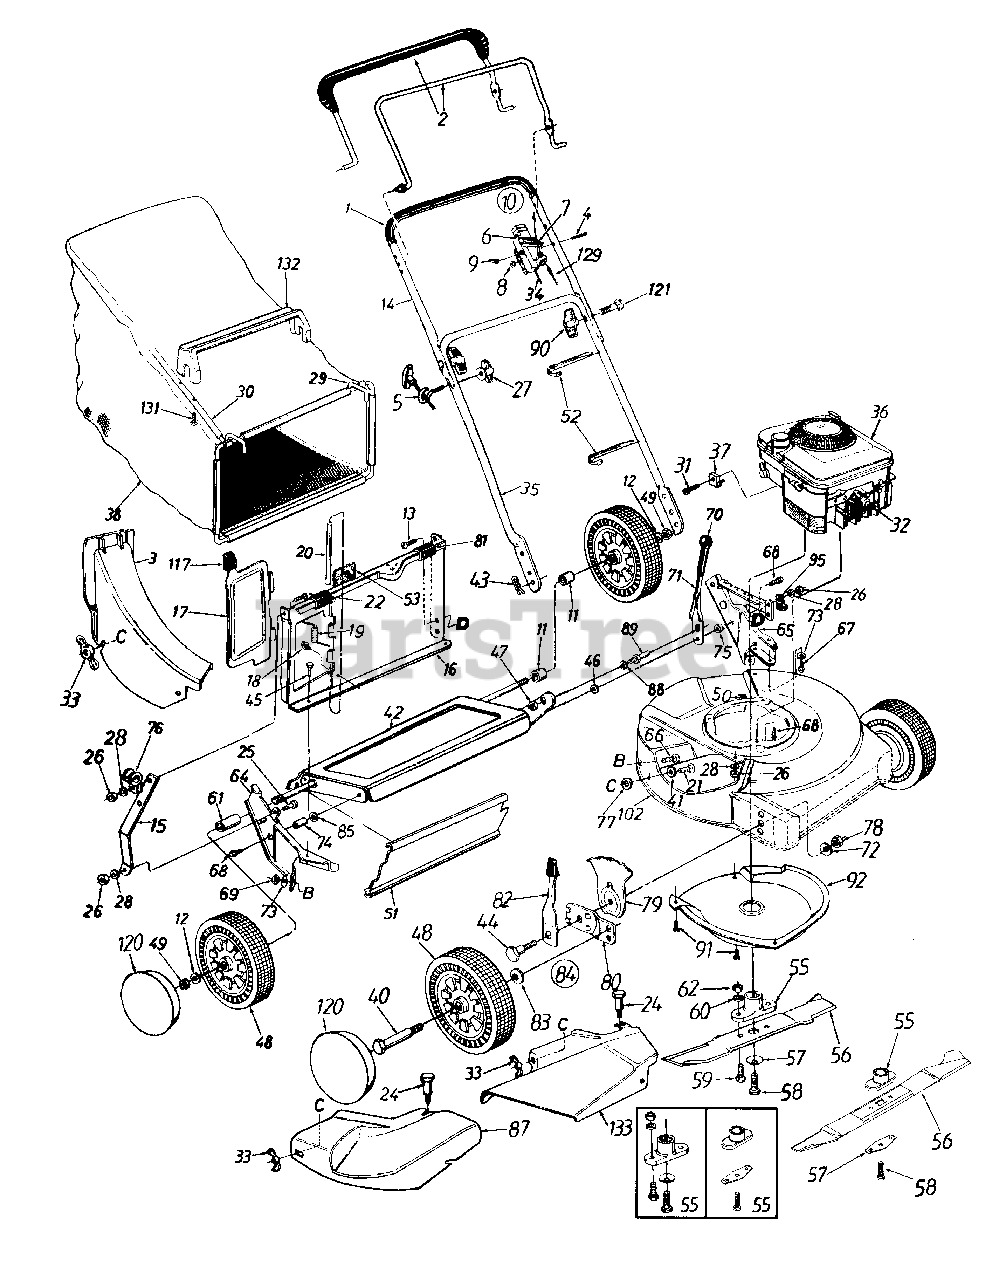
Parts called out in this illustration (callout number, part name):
1	Grip
3	Top Discharge Chute Ass'y.
4	Oval C-Sunk Scr.
5	Rope Guide
6	Throttle Body
7	Throttle Lever
8	Spr. Wash. .66" I.D.
9	Hex L-Nut 1/4-20 Thd.
10	Throttle Box Comp.
11	Spacer .526" I.D. x .690" O.D. x 640"
12	Fl-Wash. .385" I.D. x 1.0"
13	Truss Mach. Scr. 1/4-20 x .75"
19	Torsion Spring
20	Pivot Pin
21	Carriage Bolt 1/4-20 x .62"
22	Truss Mach. Scr. 1/4-20 x .75"
24	Shldr Bolt .312" Dia. x .18" L Spec.
25	Hex Bolt 1/4-20 x .62" Lg.
26	Hex Nut 1/4-20 Thd.
27	Handle Knob 1/4-20 Thd.
28	L-Wash. 1/4" I.D.
31	Hex Self-Tap Scr. #10-32 x .62"
32	Spark Plug Insulator
33	Wing Nut w/Washer
34	Throttle Control Wire 61"
36	Engine
37	Cable Clamp
38	21" Top Discharge Grass Bag
40	Shld. Bolt .498" Dia. x 1.45"
41	Fl-Wash. .344" I.D. x .62"
44	Shld. Bolt .5" Dia. x .357"
45	HexIndWsh Scr. 1/4-14:.625"
46	Fl-Wash. .38" I.D. x 1.0"
47	Hex Jam Nut 3/8-24 Thd.
48	Wheel Ass'y. Comp. S Wave Gray
49	Top L-Jam Nut 3/8-16 Thd.
51	Rear Flap
52	Cable Tie
53	Foam Strip 1" Lg.
55	Blade Adapter Kit
56	21" Mulching Blade
57	Bell-Wash. .39" I.D.
58	Hex Bolt 3/8-24 x 1.5" Lg.
59	Hex Bolt 3/8-24 x 1" Lg.
60	L-Wash. 3/8" I.D.
61	Sleeve .526" I.D. x .69"
62	Hex Nut 3/8-24 Thd.
67	Hex Hd. B-Tap Scr. 5/16-18
68	Hex Wash. Hd. TT-Tap Scr. 3/8-16
69	Hex Nut 5/16-18 Thd.
71	Height Adj. Lever
72	Bell-Wash. .39" I.D. x 1.38" O.D.
73	Bell-Wash. 5/16" I.D.
74	Spacer .383" I.D. x .503" O.D.
75	Shld. Spacer .500" Dia.
76	Rope Guide
77	Bolt Retainer 1/4 x .50" O.D.
78	Hex Nut 3/8-16 Thd.
79	Height Adj. Plate
81	Panel Clip
82	Spring Lever Ass'y w/knob
83	Bell Wash. .38" I.D. x .88" O.D.
84	Height Adj. Ass'y Comp. - R.H.
85	Fl. Wash. 3/8" I.D. x 1" O.D.
87	Mulching Plug
88	L-Wash. 3/8" I.D.
89	Shld. Pin 3/8-24 x 1.43" Lg.
90	Hand Knob
91	HxIndWash Scr. TT 1/4-20: .375
120	Hub Cap
121	Curved Hd. Bolt 5/16-18 x 2" Lg.
129	Control Cable - 44" Lg.
131	Hex AB-Tap Scr. #12 x 1.0"
132	Bag Handle
133	Side Chute Deflector Ass'y.
